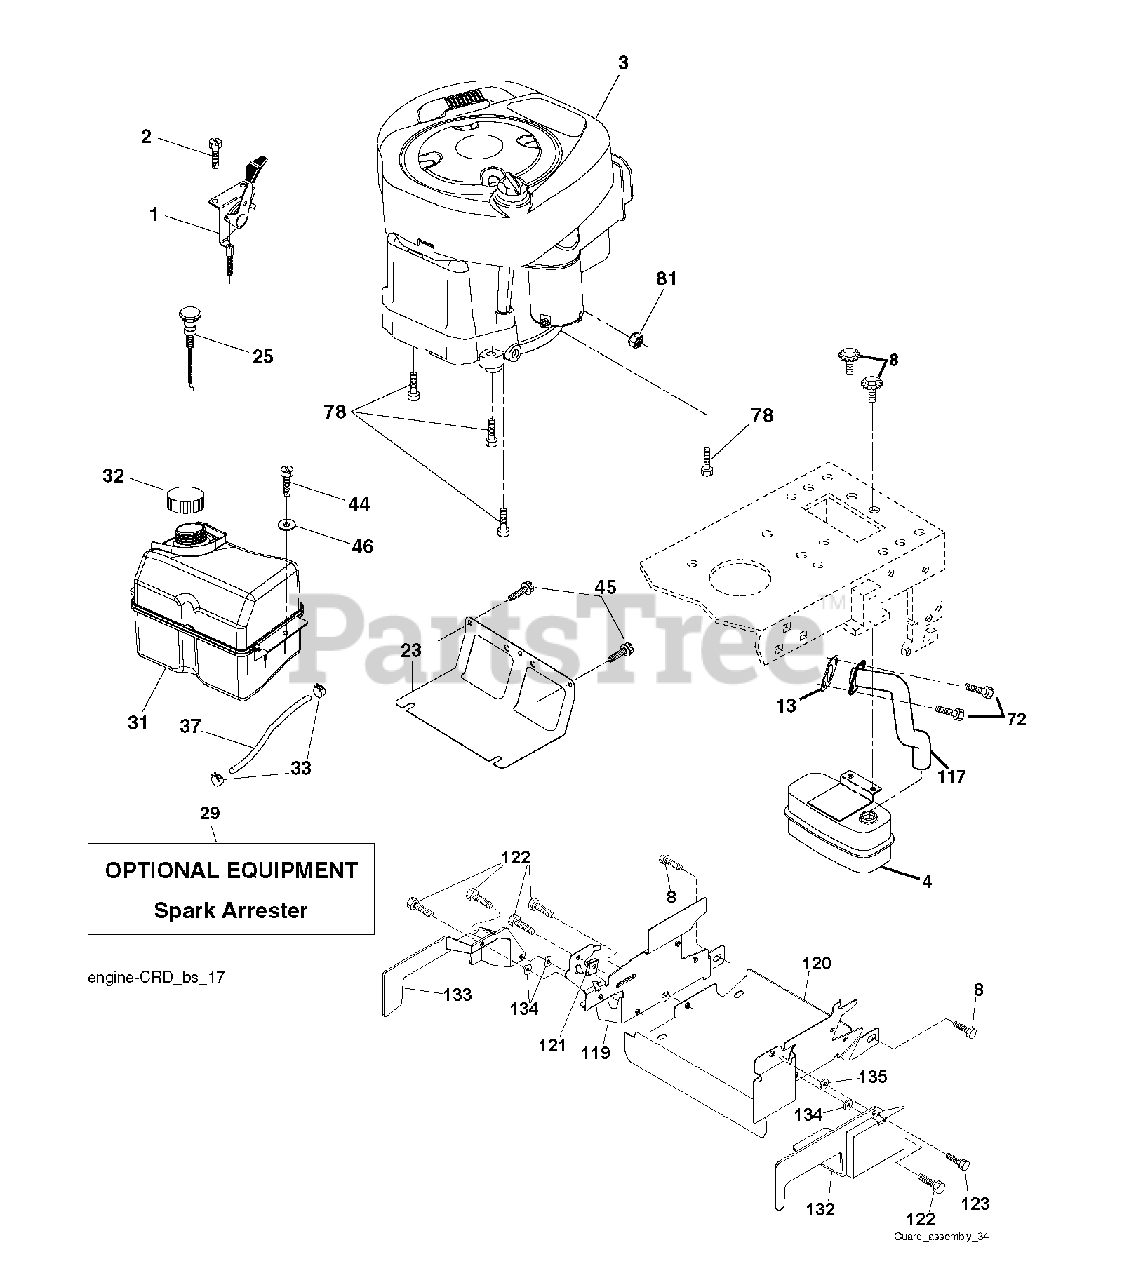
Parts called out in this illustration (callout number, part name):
1	CONTROL TH/CH FLAG
2	SCREW
4	MUFFLER.SINGLE.CYL.KOHL/B&S
8	BOLT, 5/16-18 X 1 3/4
13	REPL BY 532 27 22-93
23	SHEILD.BROWNING.DBR.GUARD
29	ARRESTER SPARK (OPTIONAL)
32	FUEL CAP
33	HOSE CLAMP
37	LINE.FUEL.20
44	SCREW HEXWSHR 1/4-20X3/4
45	SCREW, 3/8-16X3/4
72	SCREW.SOCKET HD.5/16-1
78	SCREW.3/8-16
81	NUT
117	EXHAUST.TUBE.B&S.
122	SCREW.1/4-20X5/8
123	SCREW, 5/16-18 X 1/2
134	PALNUT 1/4
